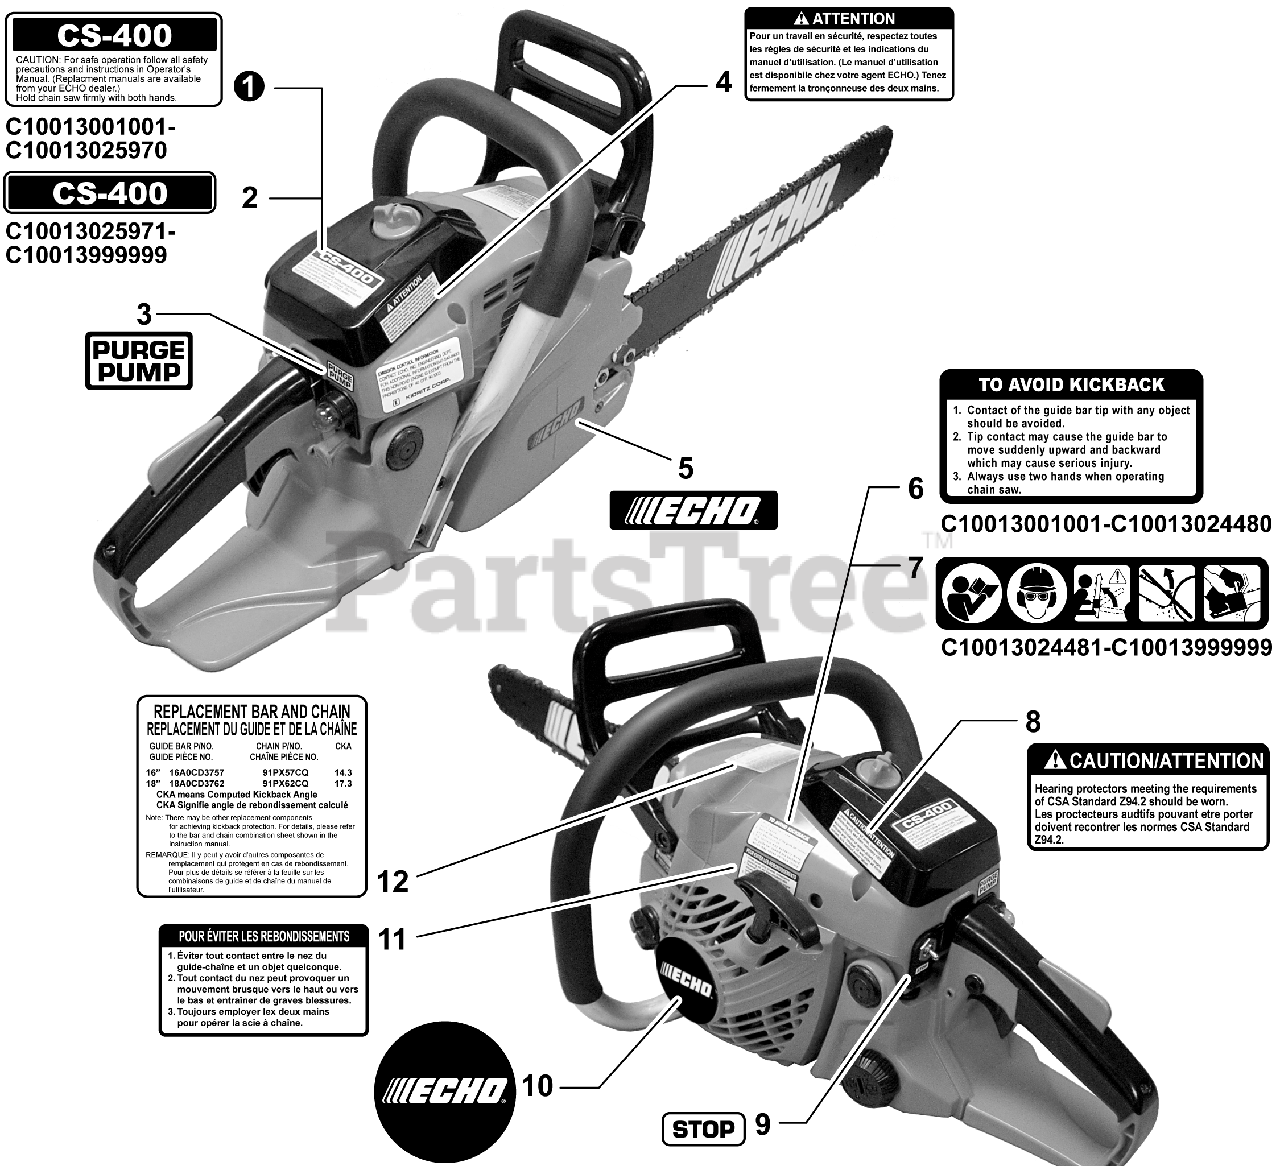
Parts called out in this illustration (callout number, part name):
1	LABEL - MODEL CS-400
2	LABEL - MODEL CS-400
3	LABEL, PURGE PUMP
4	LABEL, ATTENTION - CANADA
5	LABEL, ECHO
6	LABEL, KICK BACK
7	LABEL, CAUTION
8	LABEL, NOISE - ENGLISH/FRENCH
9	LABEL, STOP
10	LABEL, ECHO
11	LABEL, KICK BACK - FRENCH
12	LABEL, BAR & CHAIN - CANADA
